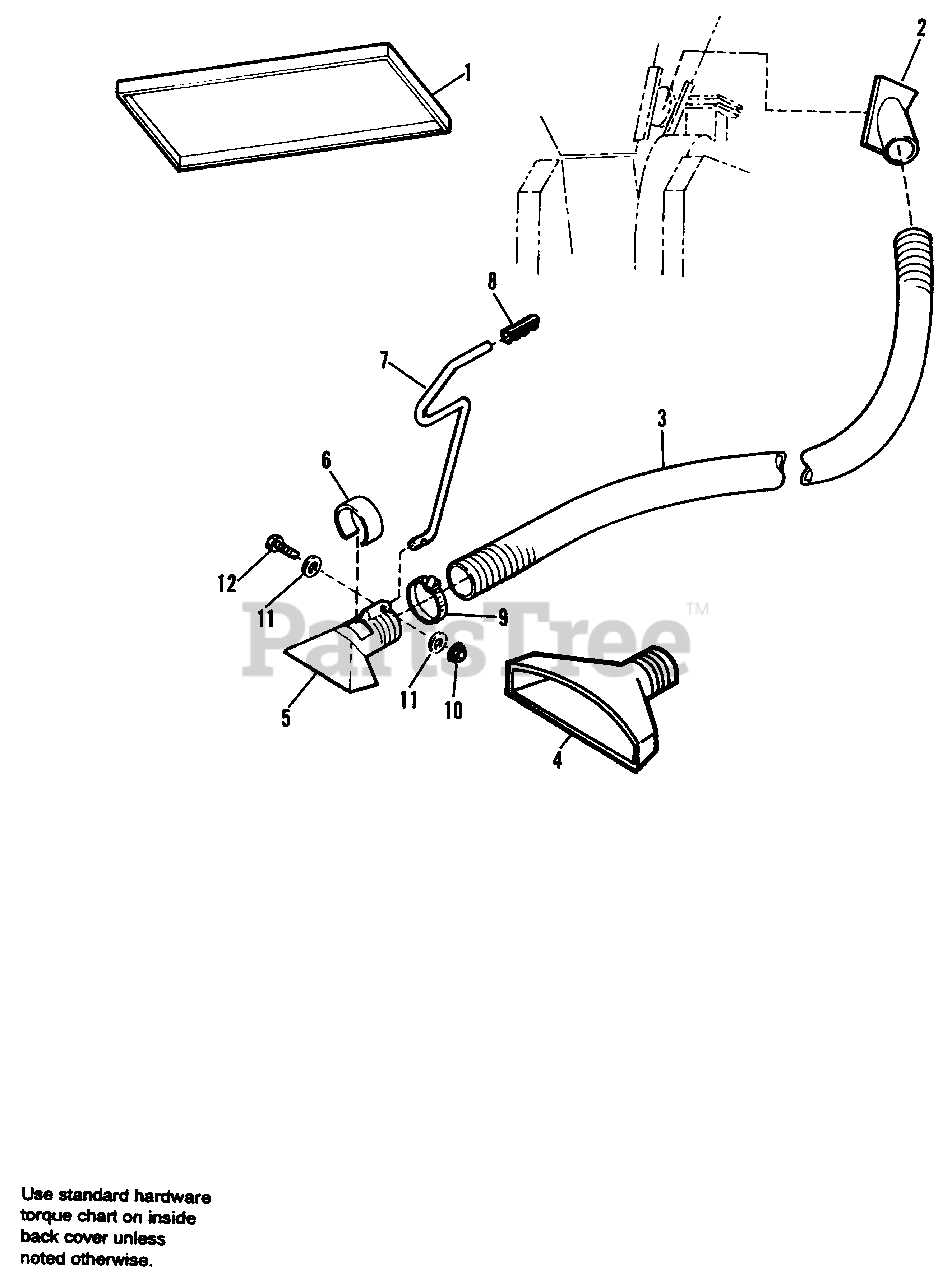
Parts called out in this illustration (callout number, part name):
1	COVER, Hopper, 23 HP
1	COVER, Hopper, 20 HP
2	ADAPTER, Hose, 23 HP
2	ADAPTER, Hose, 20HP
3	HOSE, Accessory, 5" x 16-1/2"
6	VACUUM RING
7	HANDLE, NOZZLE
8	HANDLE, Grip
9	CLAMP, Hose
10	NUT, Hex, Flange
11	WASHER
12	CAPSCREW, Hex, 1/4-20 x 1-1/2
